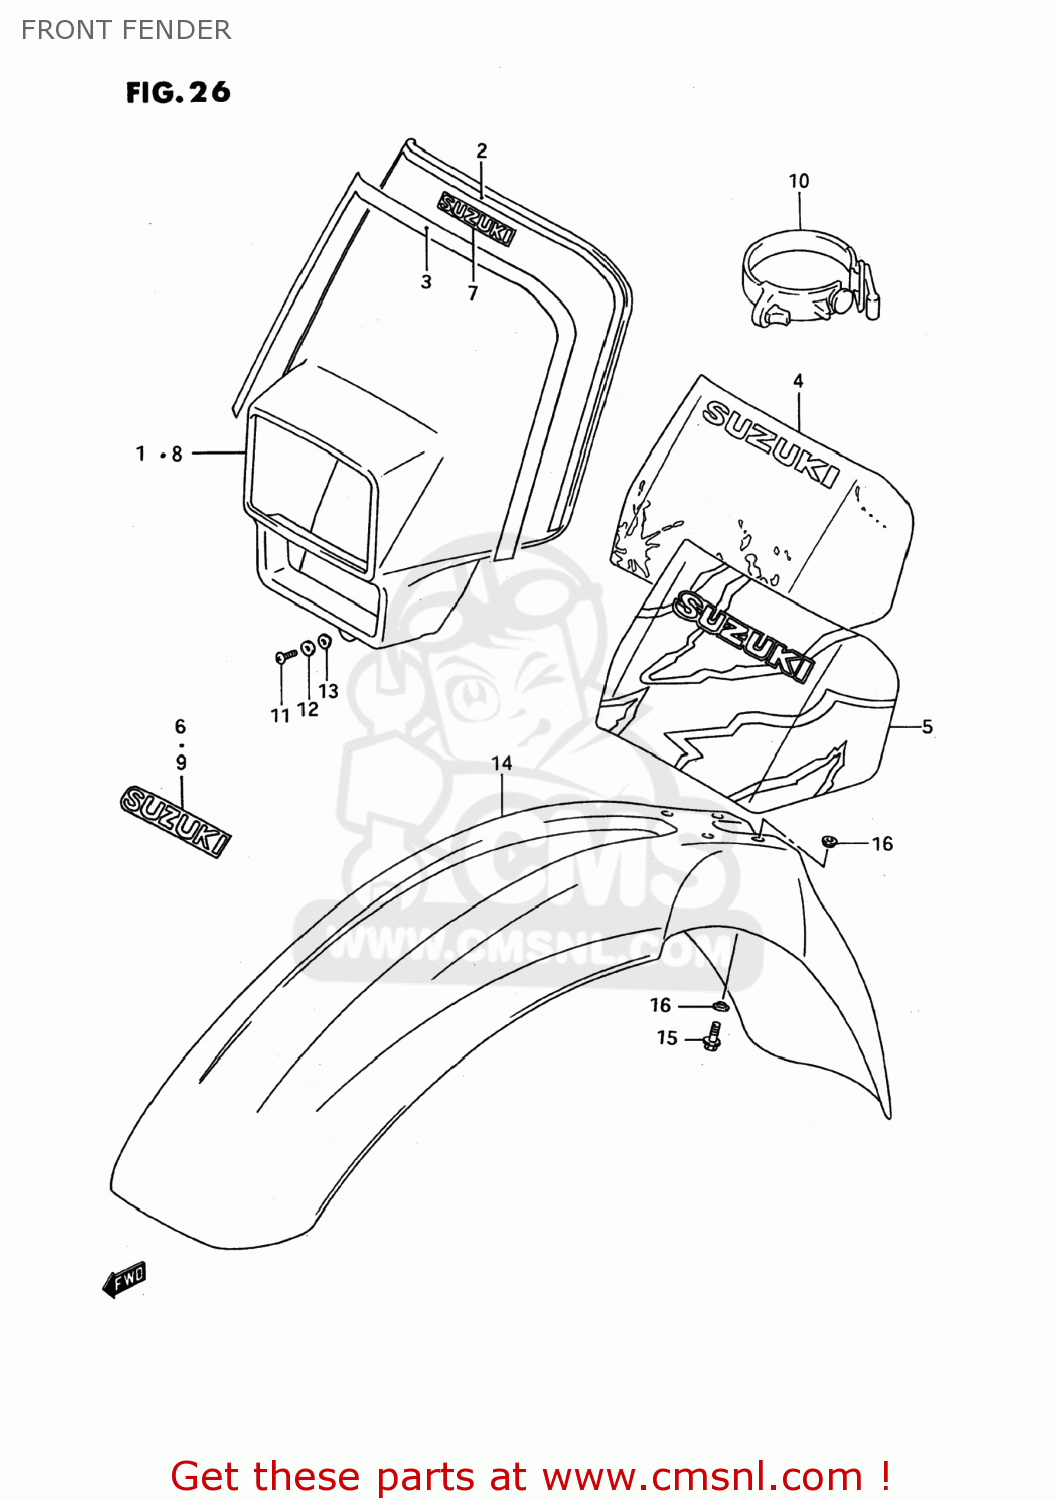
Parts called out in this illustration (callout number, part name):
1	COVER,HEADLAMP(YELLOW)
2	TAPE,HEADLAMP HOUSING
3	TAPE,HEADLAMP COVER
4	TAPE,HEADLAMP COVER
5	TAPE,HEADLAMP COVER
6	EMBLEM,SUZUKI(YELLOW/PURPLE)
7	EMBLEM,HEADLAMP HOUSING
8	COVER,HEADLAMP
9	EMBLEM,HEADLAMP COVER
10	BAND,HEADLAMP COVER
11	SCREW
12	WASHER
13	WASHER
14	FENDER,FRONT
15	BOLT
16	WASHER
